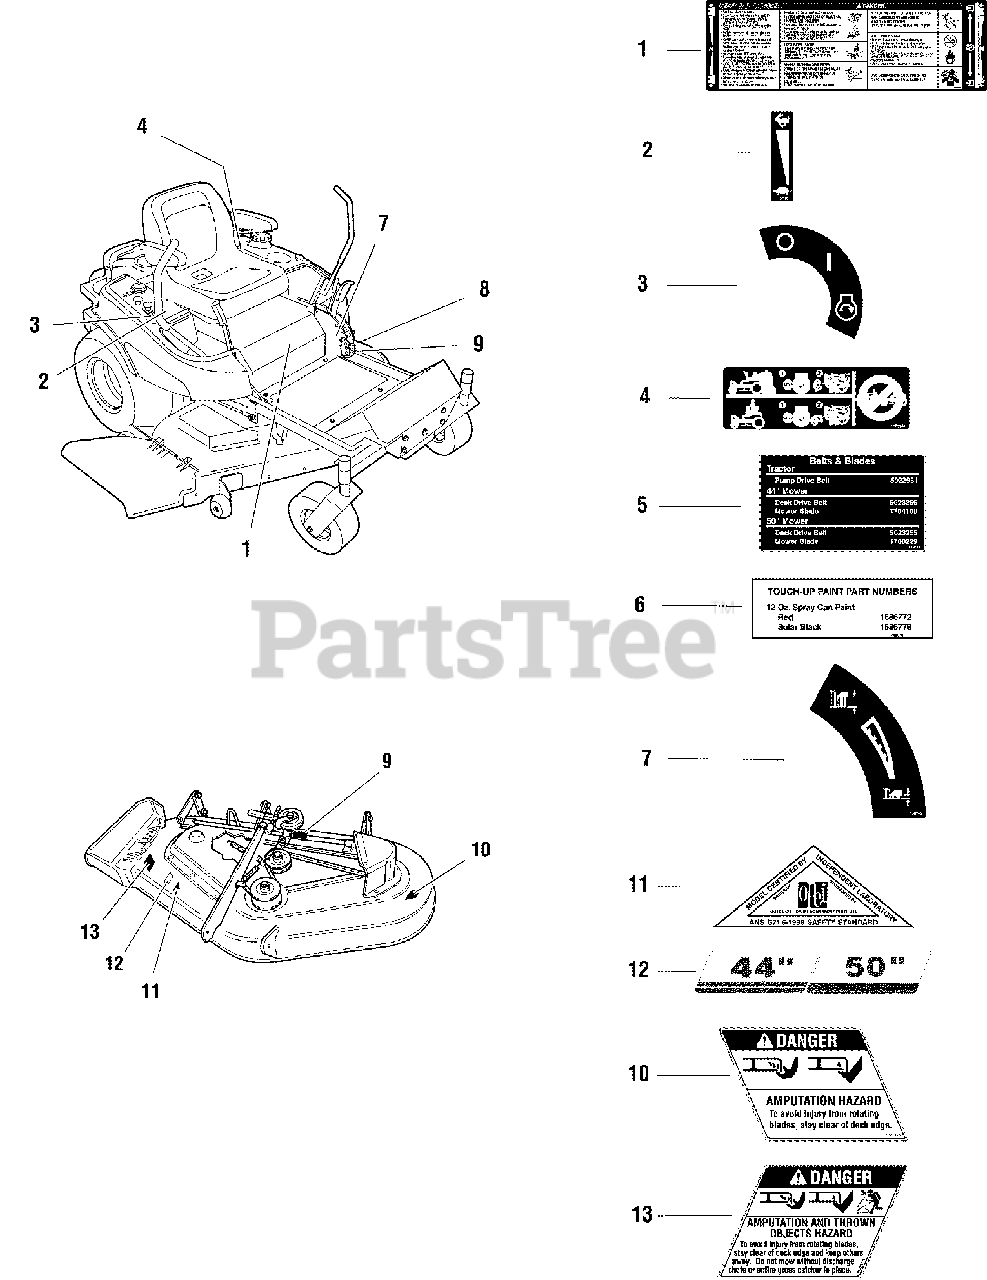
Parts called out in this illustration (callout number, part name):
1	DECAL, MAIN
2	DECAL, THROTTLE CONTROL
3	DECAL, IGNITION SWITCH
4	DECAL, CZT HYDRO RELEASE
5	DECAL, BELT & BLADE
6	DECAL-TOUCH UP PAINT
7	DECAL, HEIGHT OF CUT
8	DECAL, US PATENT, ZTR
9	DECAL, ID PLATE
10	DECAL, DANGER, MOWER
11	DECAL-OPEI CERTIFIED ANSI B71.12003 GOLD
12	DECAL-50"- SILVER ON BLACK W/STRIPE
12	DECAL-44"- SILVER ON BLACK W/STRIPE
13	DECAL, DANGER, MOWER DISCHARGE
